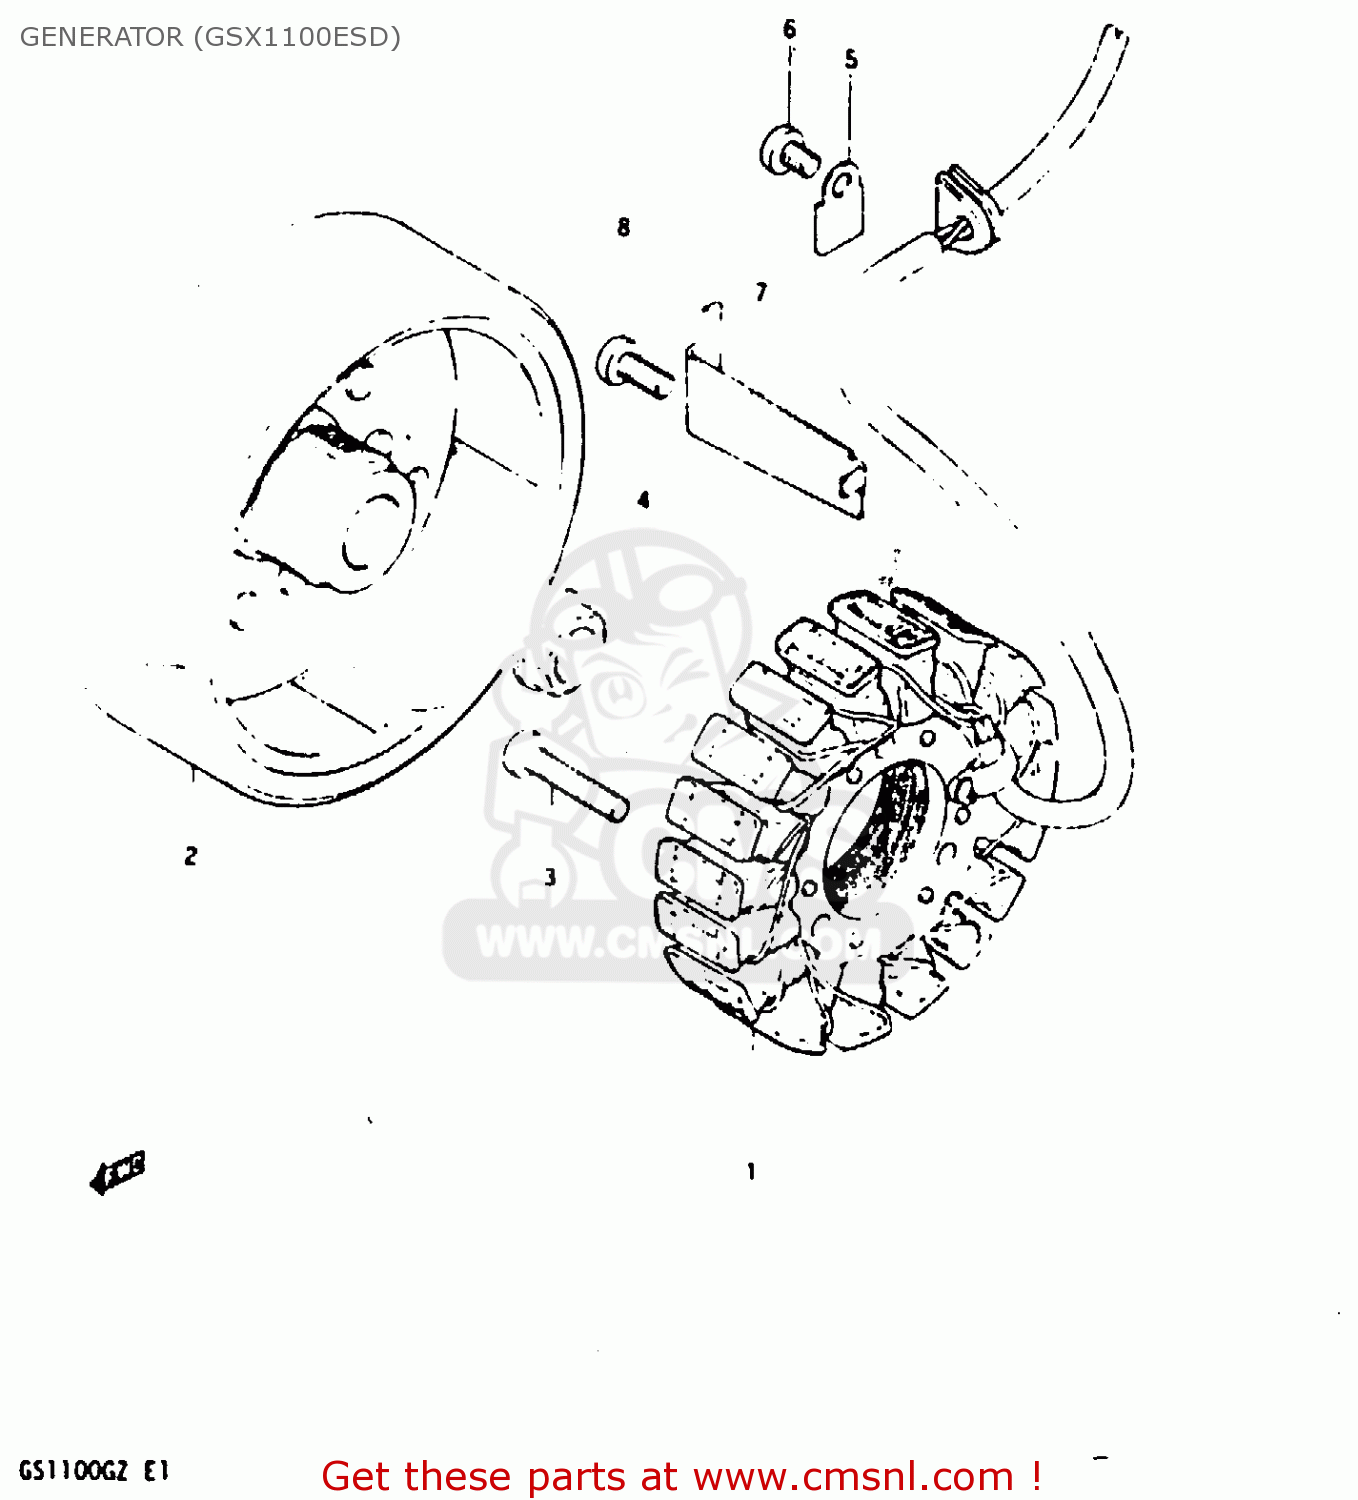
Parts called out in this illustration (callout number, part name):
1	STATOR ASSEMBLY
2	ROTOR ASSY
3	SCREW 6X30
4	NUT,GENERATOR ROTOR
5	CLAMP,GENERATOR LEAD WIRE
6	SCREW
7	CLAMP,GENERATOR LEAD WIRE
8	SCREW
